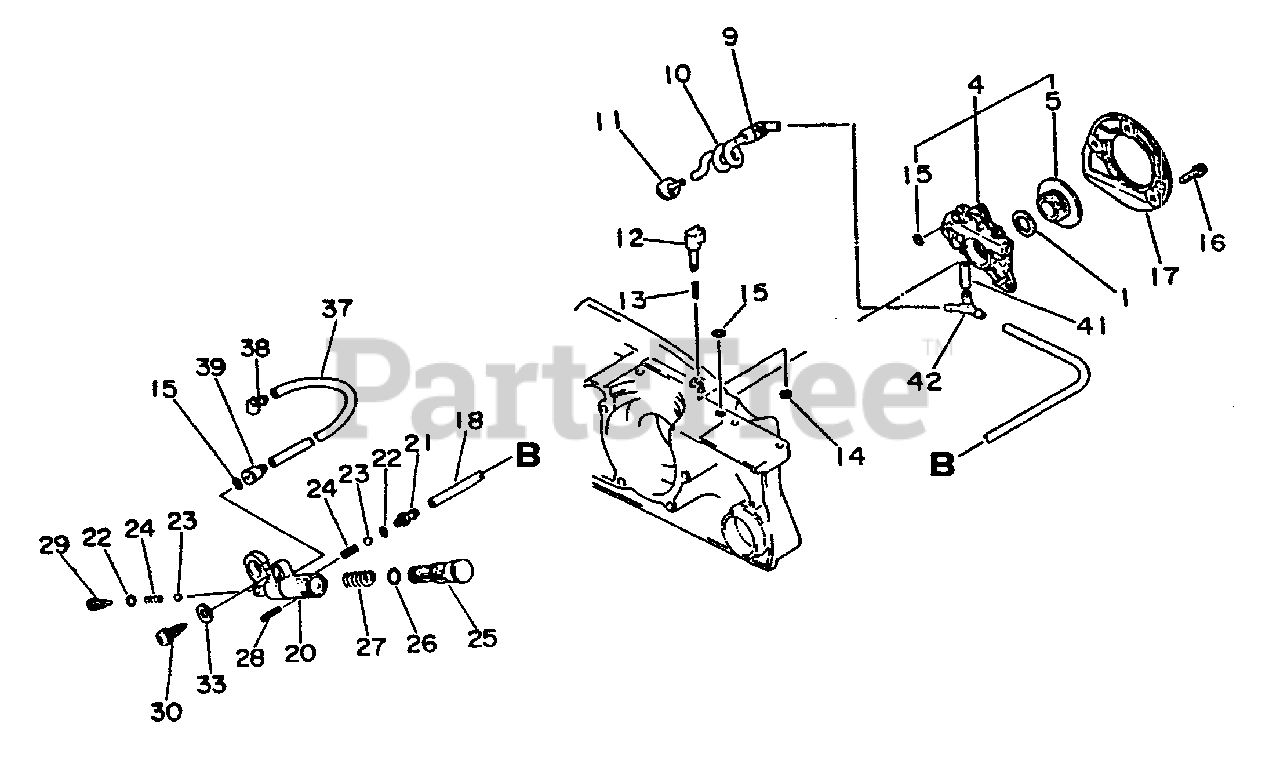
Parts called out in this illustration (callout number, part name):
4	AUTO-OILER ASSY
5	WHEEL, WORM
10	PIPE - OIL
11	FILTER, OIL
12	DIAL, AUTO-OILER
14	RING, RETAINING - 3
15	O-RING - 3
16	SCREW - 4X14
17	COVER, OIL PUMP
18	PIPE - 3X6X200 -- BLACK
20	BODY, OIL PUMP
23	VALVE, BALL
24	SPRING, VALVE
25	PISTON, OIL PUMP
26	O-RING - 7
28	PIN - SPRING -- 2X16
29	ADAPTER, OIL PUMP
30	SCREW - 5X20
33	WASHER - 5
37	PIPE, OIL - 3X6X125
38	CONNECTOR, PIPE
39	CONNECTOR, PIPE
41	PIPE - 3X6X20 -- BLACK
42	CONNECTOR, PIPE
